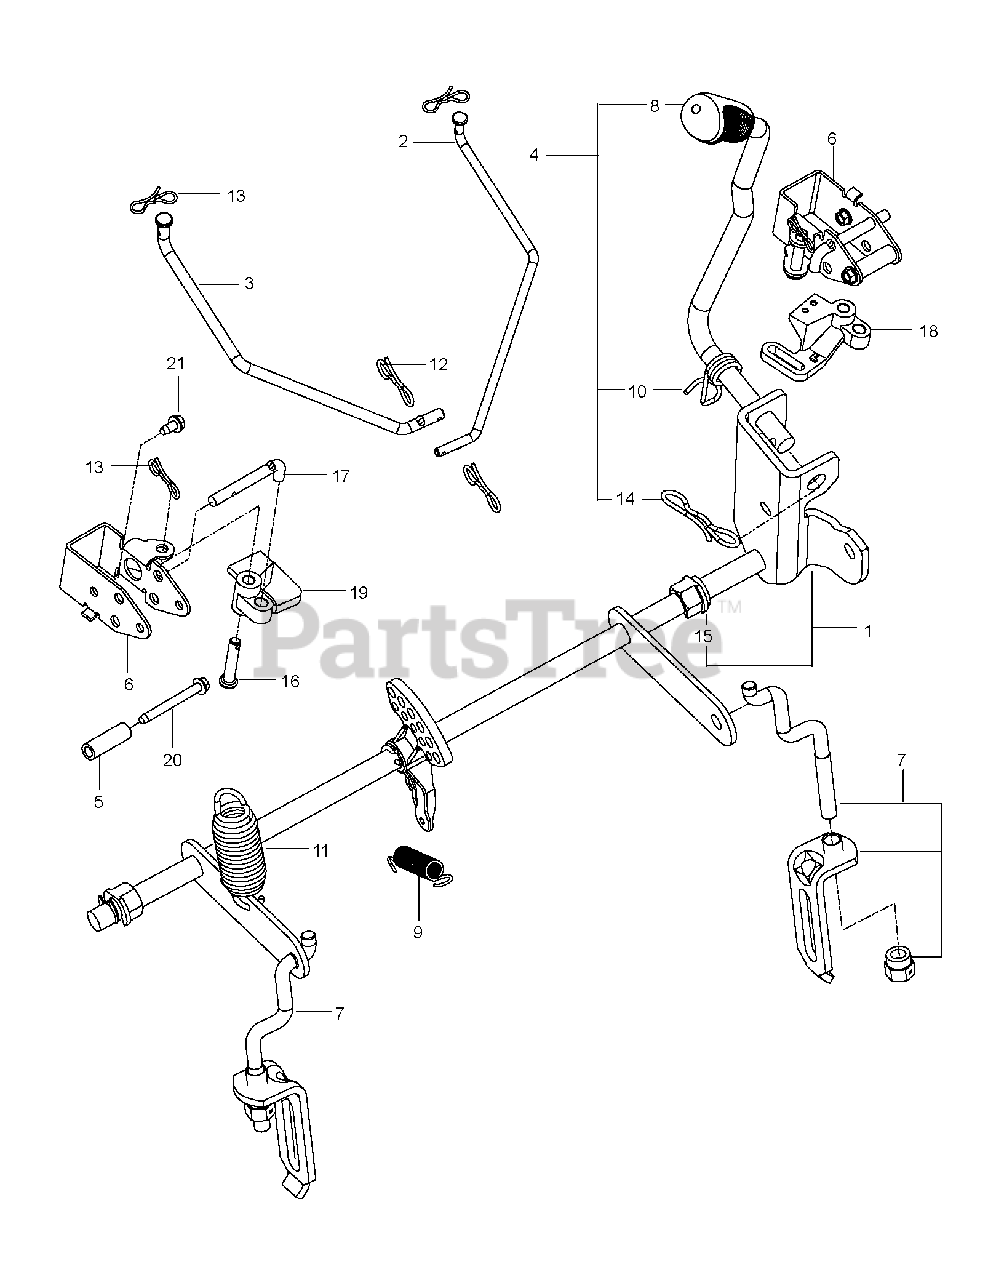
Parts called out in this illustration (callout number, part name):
1	SHAFT.ASM.RZ.DECK.LIFT.SRV
2	LINK.BRAKE.PARK.UPPER.LH
3	LINK.BRAKE.PARK.UPPER.RH
4	LIFT.LEVER.ASM.RZ.SERVICE
5	SPACER.334.ID.5.OD.1.5.L
6	BRACKET.BELLCRANK.PBRAKE X431
7	LINK.ASM.RZ.LIFT.SERVICE
8	GRIP.HANDLE.LIFT.PVC.428
9	RETURN.BRAKE.PARK.AUTO
10	SPRING.TORSION.LIFT.HANDLE
12	PIN.COTTER.5/16.BOW TI
13	PIN COTTER;LOCKING;BOWTIE;1IN
14	PIN.COTTER.7/16.BOW TI.
15	PLASTIC NUT
16	PIN.5.16X1.5
17	ROD.PUSH.BRAKE
18	BELLCRANK.LH
19	BELLCRANK.RH
20	SCREW THD;ROLL;1/4-20 X 2.25
21	SCREW.1/4-20X5/8
